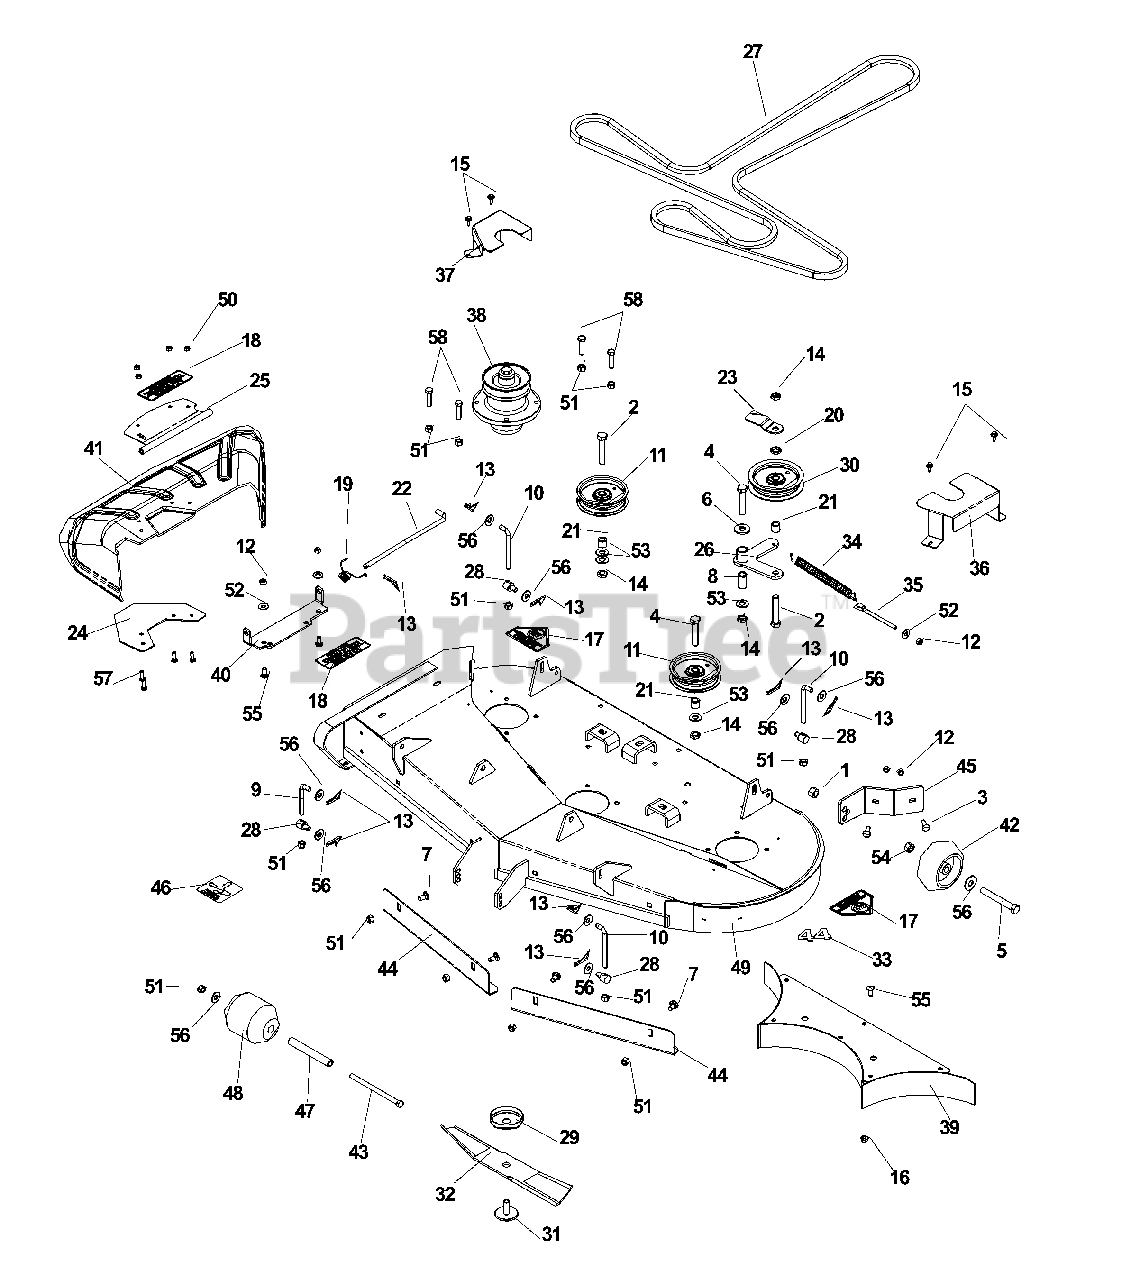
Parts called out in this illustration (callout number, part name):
1	NUT 1/2-13 HEX NYLOC ZD
2	HCS 1/2C X 2 3/4
3	RHSSNB 5/16C X 1.0
4	HEX SCREW 1/2-13 X 2.5" GR 5
5	HCS 1/2-13 X 4 GR 5 ZD
6	WASH USS FLAT 1/2
7	RHSNB 3/8-16 X 3/4 GR5 ZD
8	BUSHING DIXON 1080
9	L ROD 3-1/8"
10	L ROD 3-7/8
11	PULLEY IDLER
12	NUT 5/16 NYLOC
13	PIN, COTTER 1 3/4
14	NUT, 1/2-13 THIN PROF NYL
15	SCREW, TAP & DR #12-14 X 3/4
16	5/16-18 FLANGED L-NUT
17	DECAL, CPSC
18	DECAL, DANGER
19	DEFLECTOR SPRING
20	HD PULLEY SPACER
21	BUSHING
22	DEFLECTOR PIN
23	BELT GUARD BLK
24	DEFLECTOR BRKT
25	DEFLECTOR MT BRKT
26	IDLER WLDT.
29	TRASH GUARD
30	IDLER PULLEY
31	BLADE BOLT
32	BLD 44" HI LIFT FUS
33	DECAL, DECK 44"
34	SPRING, DECK BELT
35	EYE BOLT 4.5`
36	PULLEY GUARD
37	PULLEY GUARD
38	HUB ASM
39	44 W-BAFFLE WLDT.
41	44 DEFLECTOR
42	GAUGE WHEEL
43	BOLT 3/8 X 6 GR5
44	BLOW-BY BAFFLE
45	ROLLER BRKT.
46	DECAL, BELT ROUTING (18656)
47	BUSHING
48	ROLLER 3-3/4 DIA. X 4-1
49	DECK W/W-BAFFLE 44" DIX
50	NUT 1/4-20 NYLOC
51	NUT 3/8-16 NYLOC
52	FLAT WASHER 5/16 SAE
53	WASHER 1/2" FLAT
54	NUT HEX 1/2
55	BOLT 5/16C X 3/4" CARRIAGE
56	WASHER 3/8 FLAT
57	HCS 1/4C X 3/4 HCS
58	HCS 3/8C X 1 1/2
